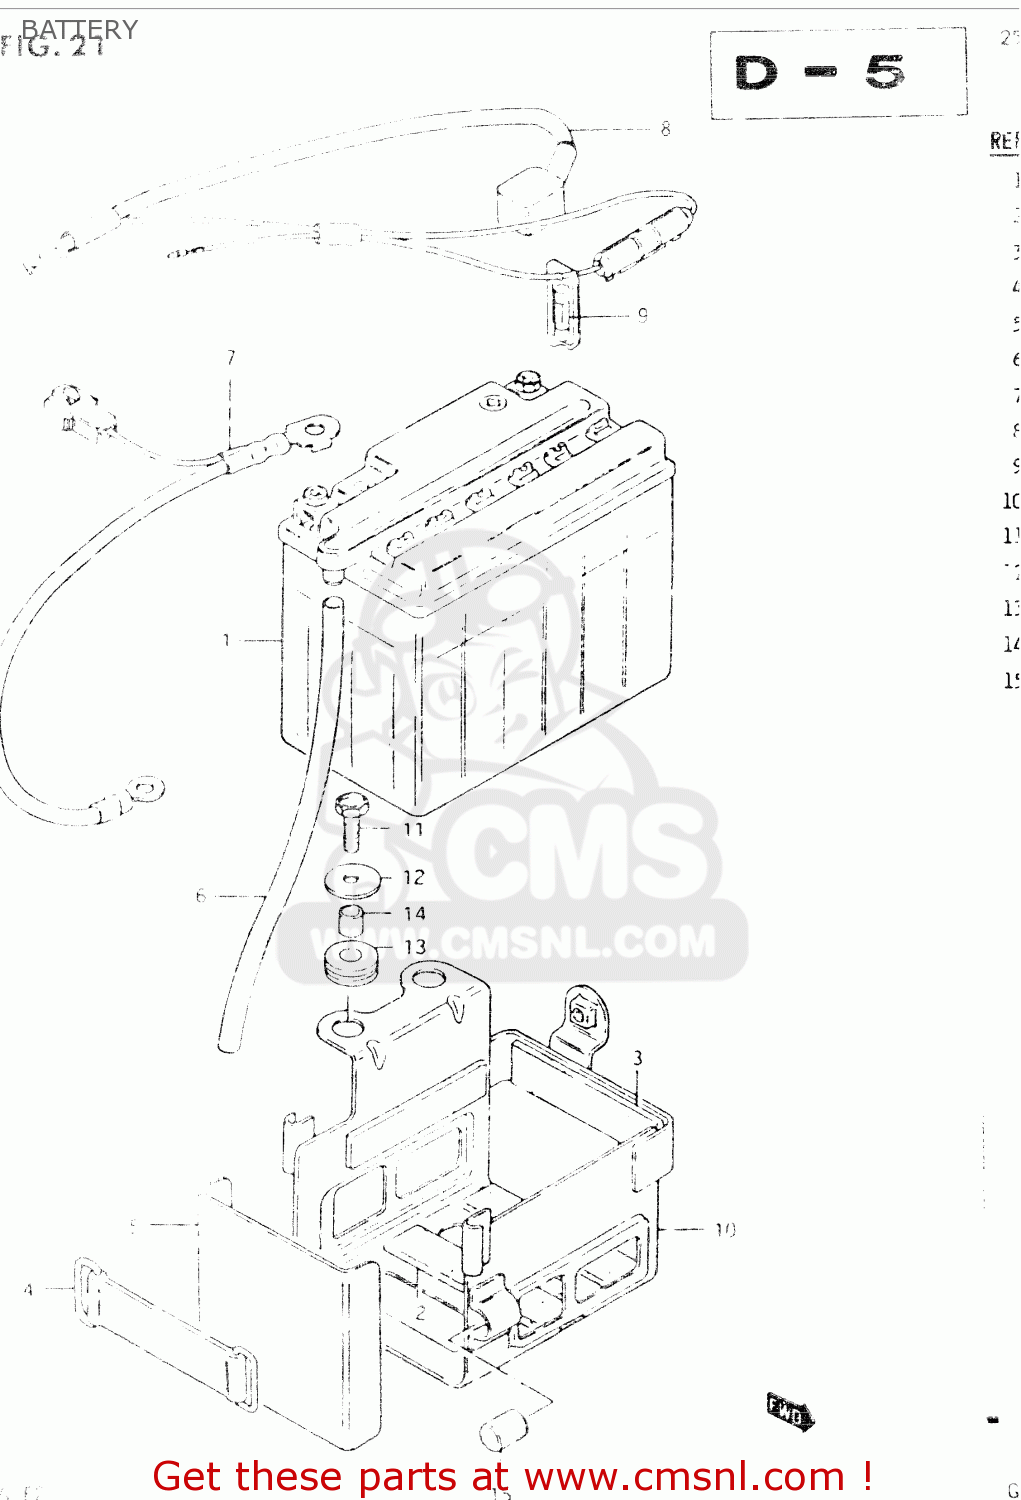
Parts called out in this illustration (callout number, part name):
1	BATTERY(YB12B-B2,12V11.6A)
2	PROTECTOR(170X95X3.0)
3	PROTECTOR,20X9
4	BAND
5	COVER,BATTERY
6	HOSE,BATTERY EXHAUST
7	WIRE,BATTERY MINUS
8	CASE ASSY,FUSE (WITH CABLE)
9	FUSE(15A)
10	HOLDER,BATTERY
11	BOLT,M6X1X20
12	WASHER
13	CUSHION
14	SPACER(6.1X9X7.5)
15	CUSHION
